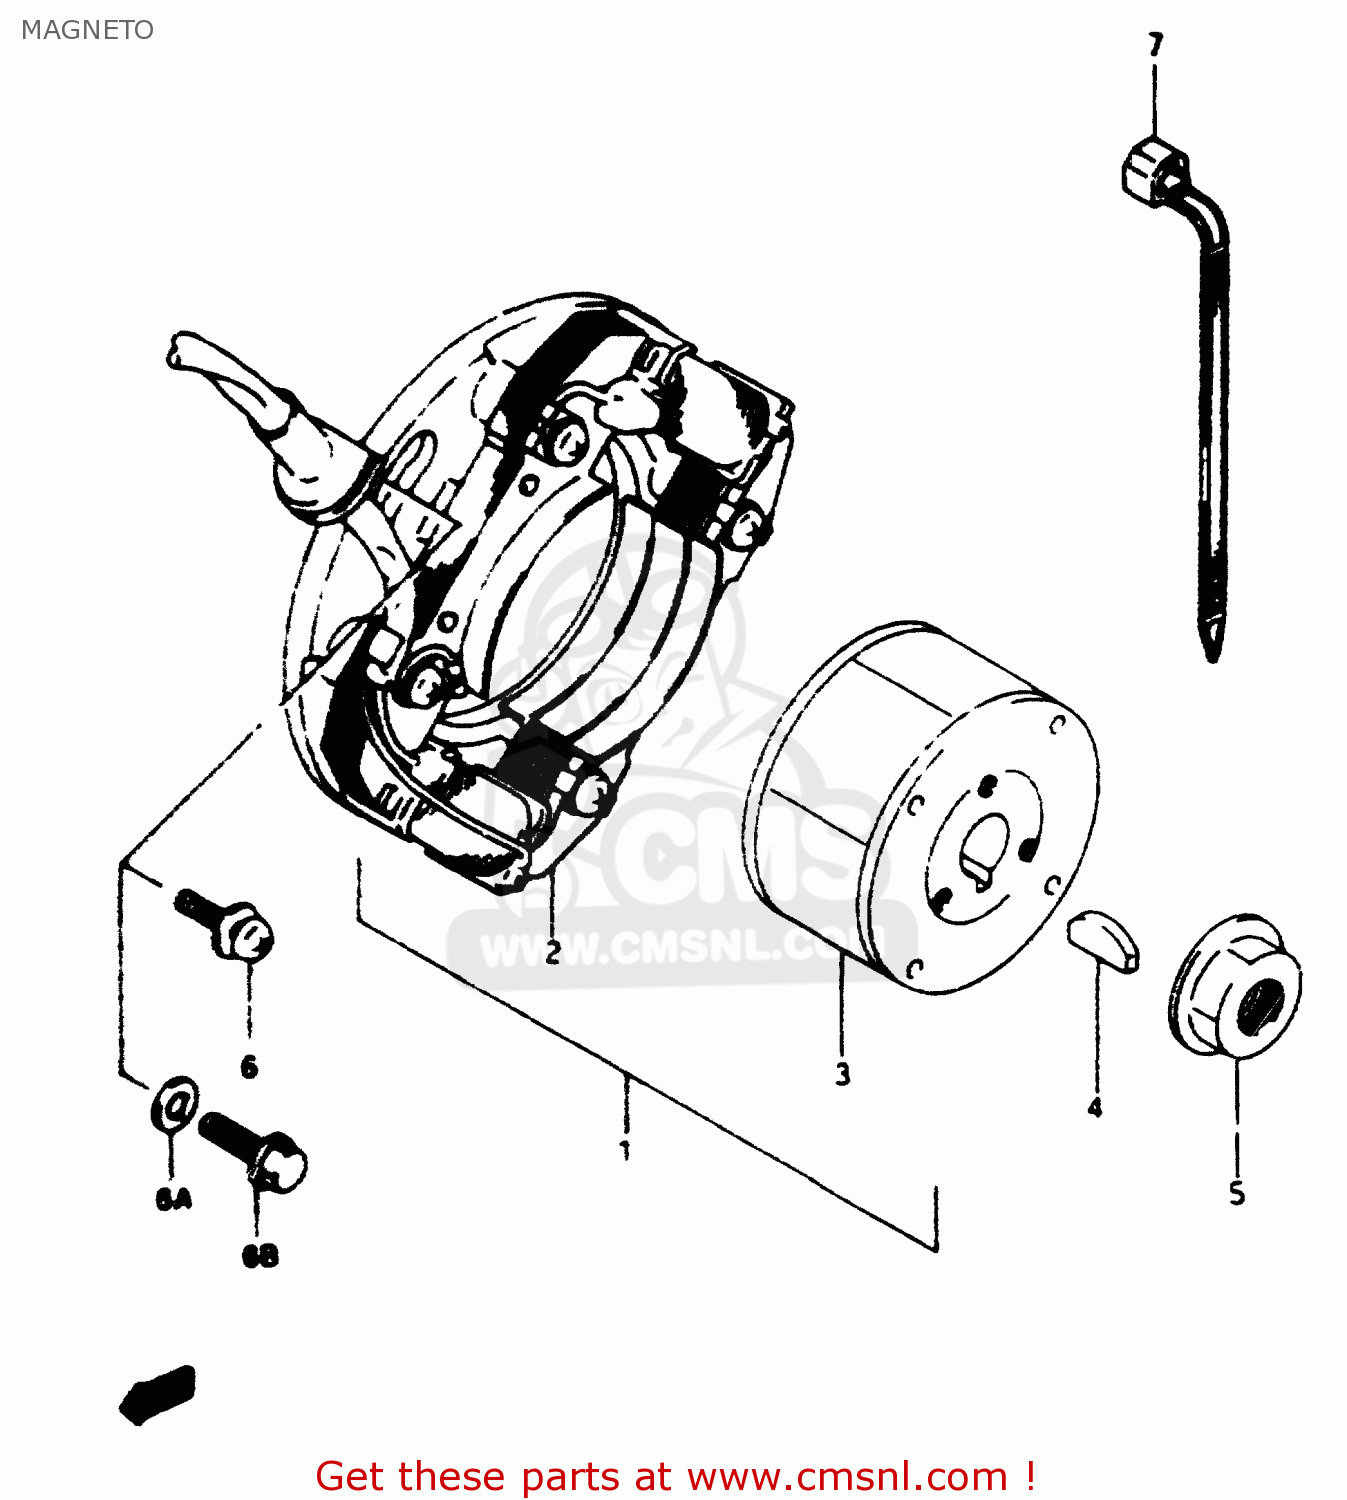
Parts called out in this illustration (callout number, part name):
1	MAGNETO ASSEMBLY
2	STATOR
3	ROTOR
4	KEY
5	NUT
6	SCREW
6A	SCREW
6B	WASHER
7	CLAMP L:165
